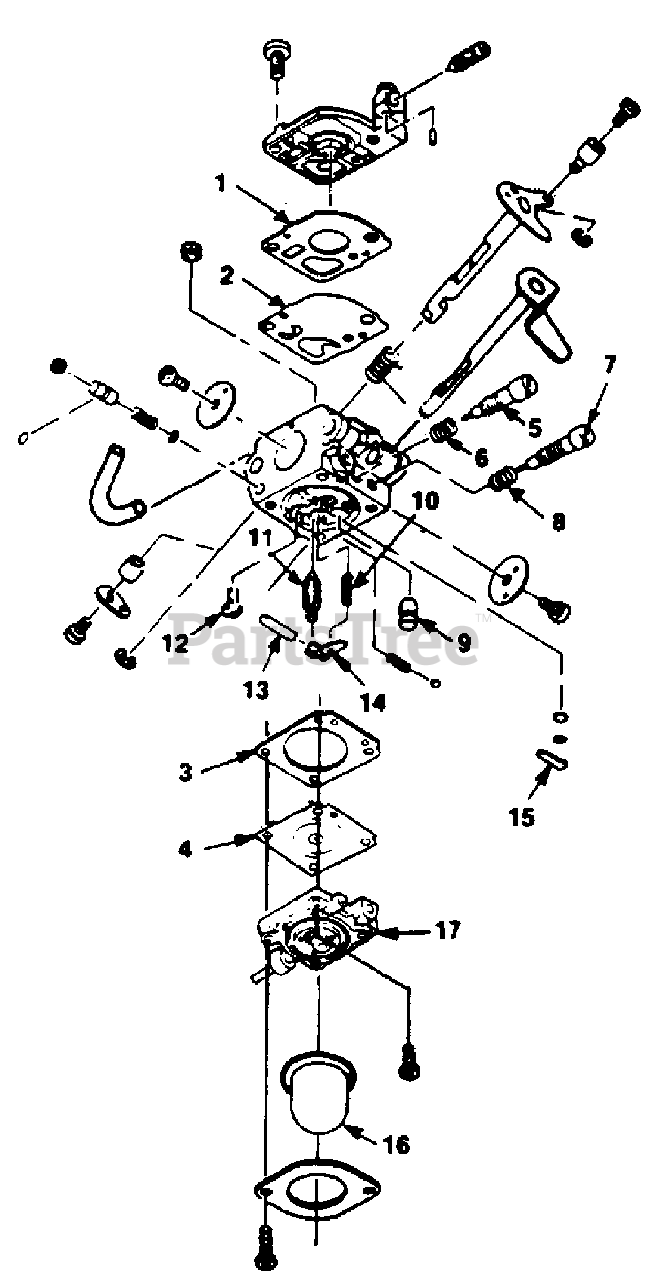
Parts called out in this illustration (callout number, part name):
1	REPAIR KIT
2	REPAIR KIT
3	REPAIR KIT
4	REPAIR KIT
5	REPAIR KIT
6	REPAIR KIT
7	REPAIR KIT
8	REPAIR KIT
9	REPAIR KIT
10	REPAIR KIT
11	REPAIR KIT
12	REPAIR KIT
13	REPAIR KIT
14	REPAIR KIT
15	REPAIR KIT
16	PRIMER BULB
17	PRIMER BASE KIT (Plastic)
